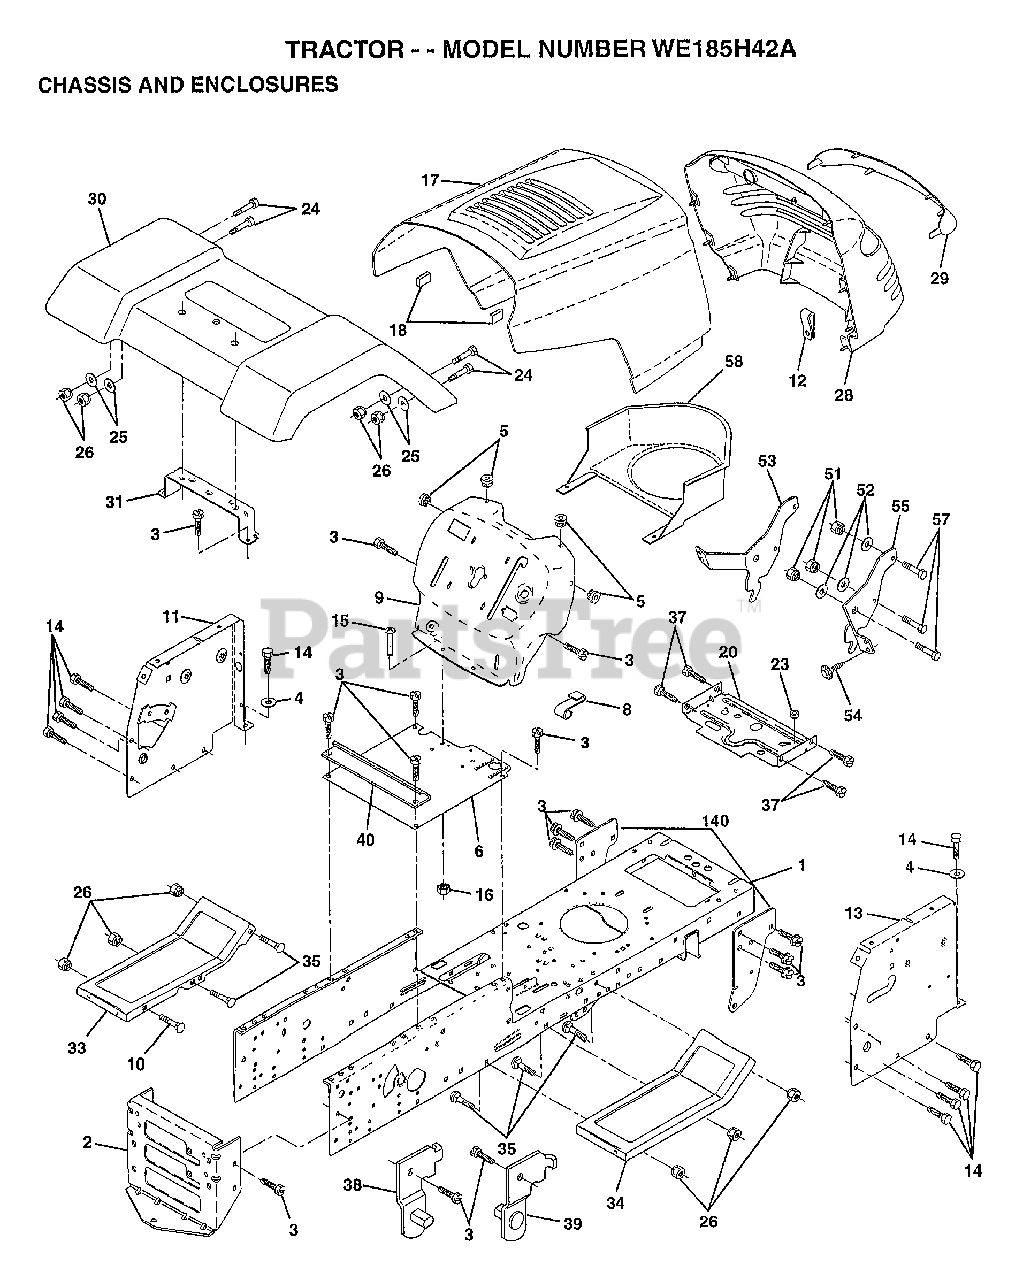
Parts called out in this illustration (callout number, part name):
1	CHASSIS ASM
3	SCREW
4	WASHER
5	BUMPER-HOOD/DASH
6	SADDLE
8	CLIP.RETAINER
9	DASH.SILKSCREENED
11	"PANEL-DASH,LH"
12	CLIP.TINNERMAN
14	SCREW LT
15	SCREW
20	"PLATE-MTG,BATT/FU"
24	BOLT
25	WASHER
26	NUT
28	GRILLE-MS428
29	LENS GRILLE
30	FENDER
31	BRACKET SUPT FEND
33	FOOTREST.LH.LT/GT
34	FOOTREST.RH.LT/GT
35	BOLT
37	SCREW LT
38	BRACKET ASM LH
39	BRACKET ASM RH
40	SPACER FENDER LT
51	NUT
52	WASHER
53	BRACKET.GRILLE.LH
55	BRACKET.GRILLE.RH
58	AIR DUCT
140	BRKT SUSPENSION
